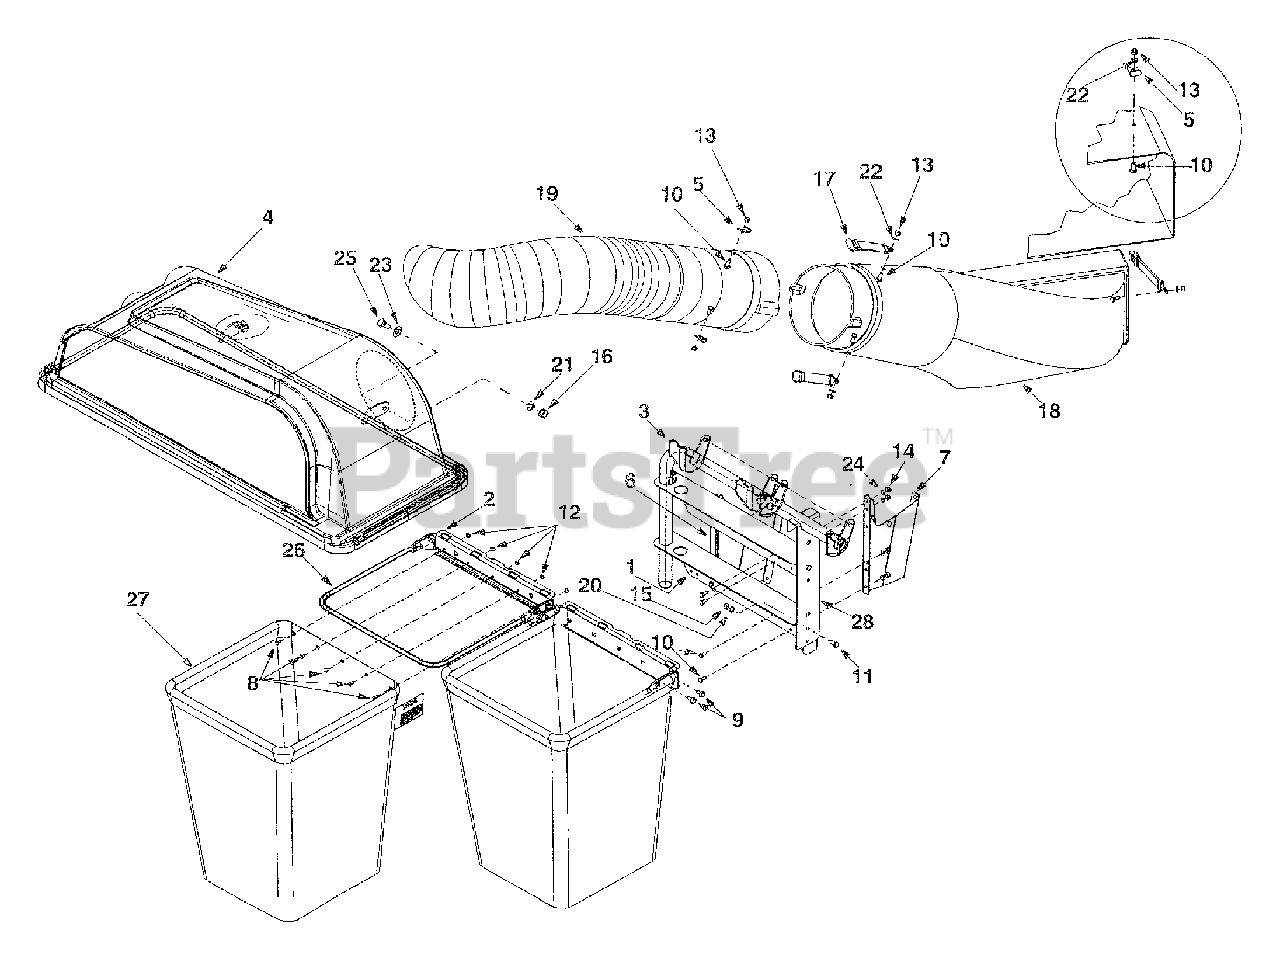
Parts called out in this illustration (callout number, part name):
4	Cover Assembly
5	Retainer Hook Bracket
8	Mach. Screw: #10-24 X 0.5"
9	Screw, TT: 5/16-18 X 0.625"
10	Hex Bolt: 1/4-20 X 0.620" Gr. 5
11	Hex Bolt: 5/16-18 X 0.75" Gr. 5
12	Hex Sems Nut: 10-24
13	Hex Lock Nut
14	Hex Nut: Gr. 5
15	Hex Nut: 5/16-18
16	Hex Nut: 318-16 Gr. 8
17	Retainer Strap Assembly
18	Discharge Chute
19	Chute Tube
20	Lock Washer: 5/16
21	Lock Washer
22	Spring Washer
23	Bell Washer
24	Lock Washer: 1/4
25	Shoulder Screw
27	Catcher Bag
